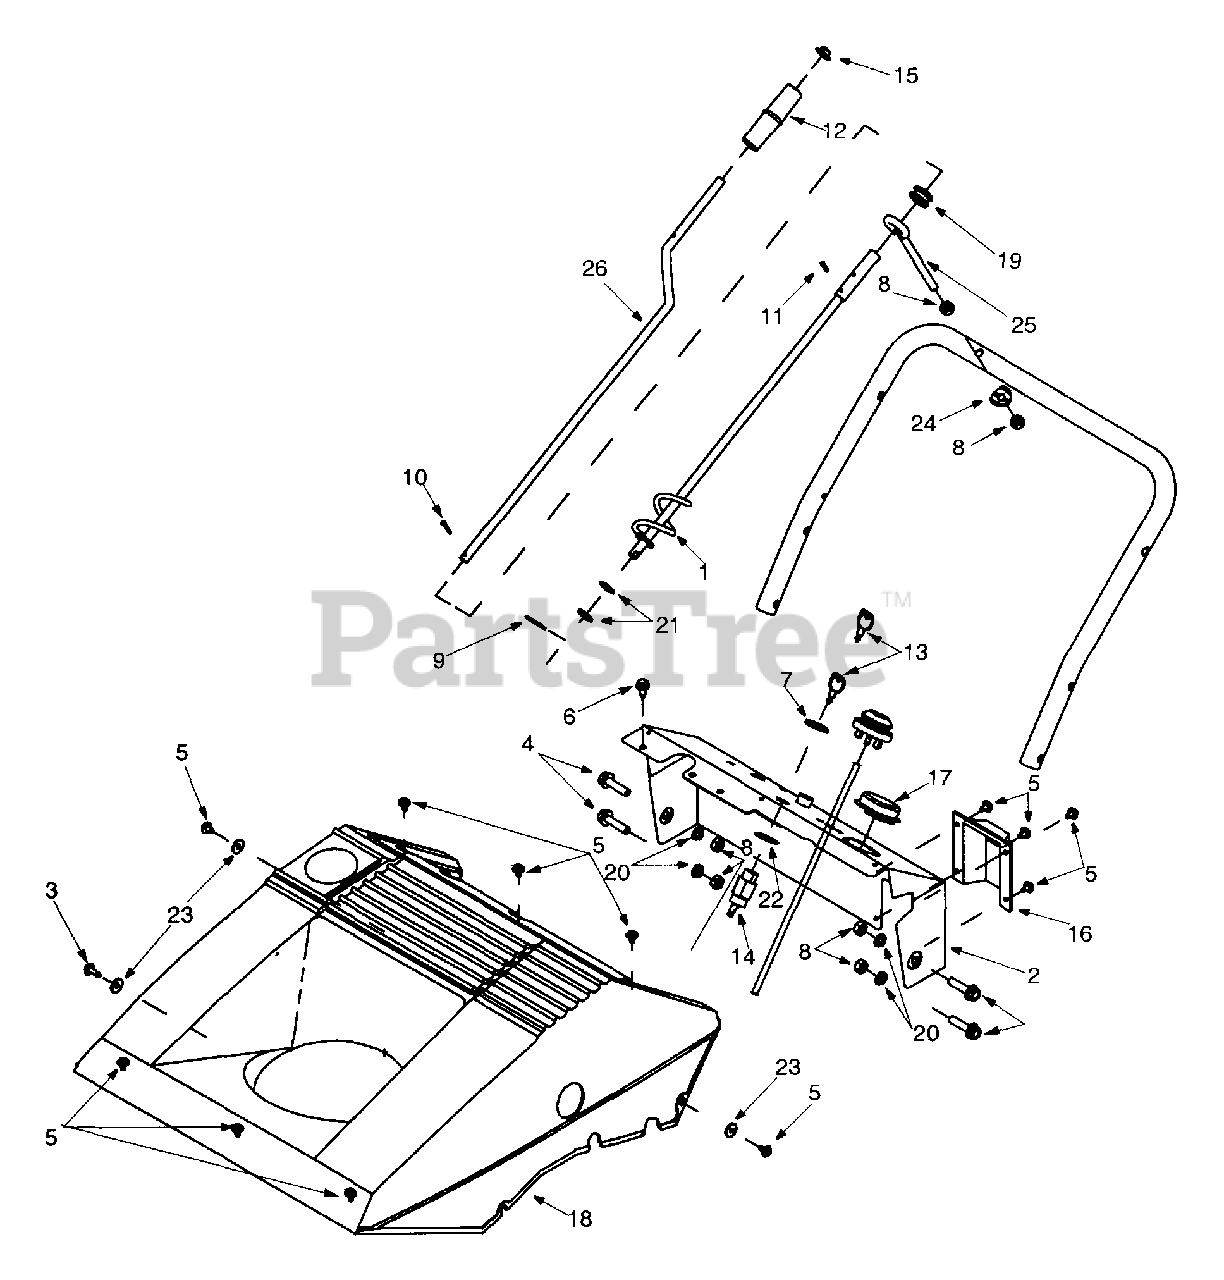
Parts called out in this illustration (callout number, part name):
4	Hex Flange Screw
5	Special Screw
6	Self-Tapping Screw
7	Jam Nut
8	Hex Nut: 5/16-18
9	Hairpin Clip
10	Cotter Pin
11	Roll Pin
13	Ignition Key
14	Key Switch
15	Push Cap
16	Choke Cover
17	Cap
18	Shroud: 21" Yellow
19	Rubber Grommet
20	Lock Washer
21	Flat Washer
22	Internal Lock Washer
23	Flat Washer
24	Saddle Washer
25	Eye Bolt
